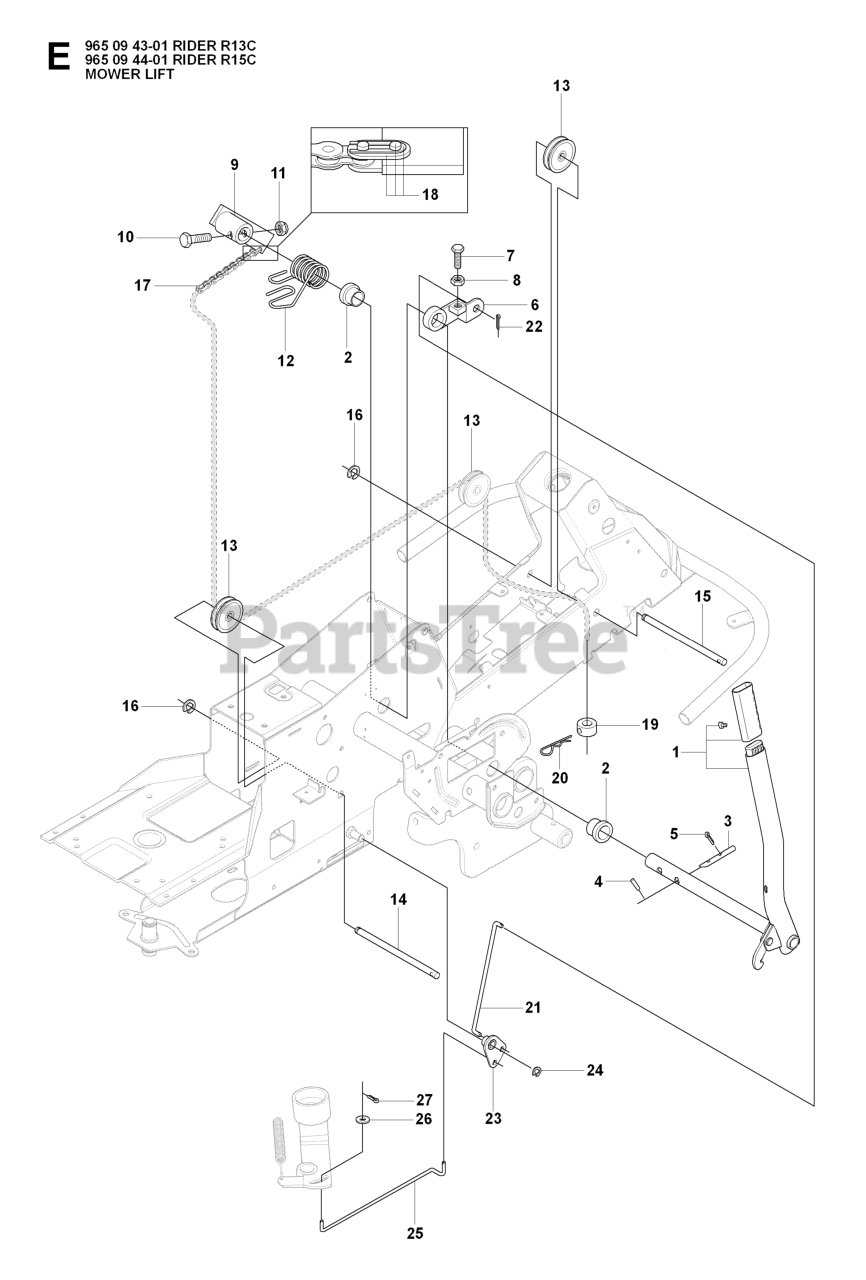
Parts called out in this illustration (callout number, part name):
1	LIFTING LEVER ASSY
2	BEARING FLANGE
3	RP PIN
6	LEVER CLUTCH
8	NUT
9	LIFTING ARM
21	CONNECTION ROD
24	RETAINING RING
25	CONNECTION ROD
